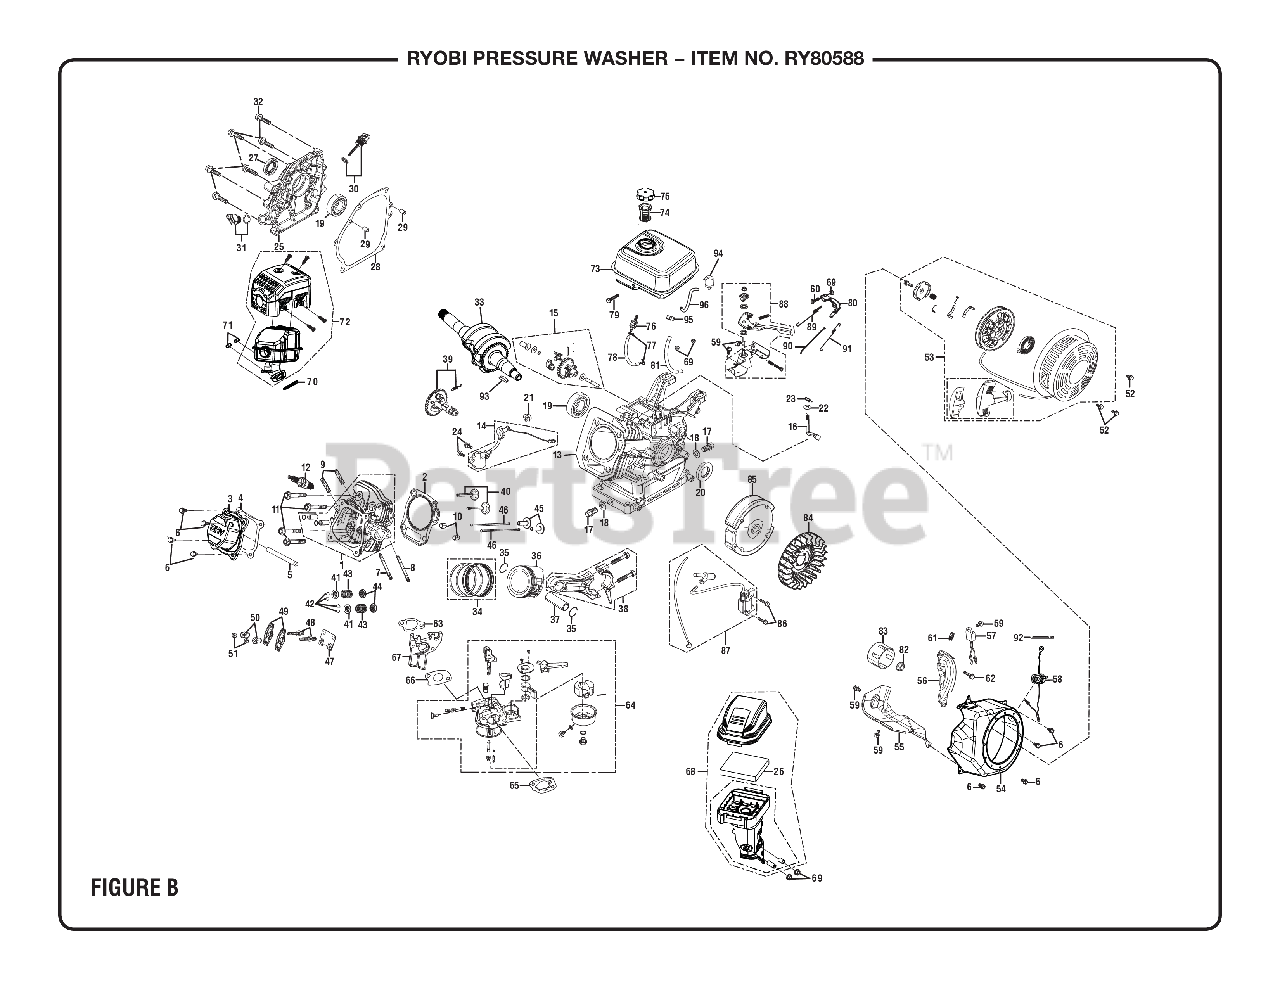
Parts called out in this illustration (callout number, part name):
1	Cylinder Head Assembly
2	Cylinder Head Gasket
3	Cylinder Head Cover Sub-assembly
4	Cylinder Head Cover Gasket.
6	Bolt (need size)
11	Bolt (Cylinder Head)
13	Crankcase Assembly
14	Engine Oil Sensor
15	Governor Gear Assembly
17	Drain Plug Bolt
19	Ball Bearing
22	Governor Gear Washer
25	Crankcase Cover Assembly
26	Air Cleaner Element Assembly
28	Crankcase Gasket
30	Oil Dipstick Sub-assembly
31	Engine Oil Plug Assembly
33	Crankshaft Assembly
34	Piston Ring Assembly
35	Piston Pin Clip
36	Piston Assembly
39	Camshaft Assembly
41	Valve Spring Seat
42	Valve Lock Clamp
47	Lifter Stopper Plate Sub-assembly
48	Valve Adjustment Bolt
50	Valve Adjustment Nut
53	Recoil Starter Assembly
55	Shroud (flasque de cylindre)
58	Stop Engine Switch Assembly
60	Governor Support Bolt,
63	Carburetor Insulator Gasket..
64	Carburetor Assembly
65	Air Cleaner Gasket
66	Carburetor Gasket
67	Carburetor Insulator Plate
69	Governor Support Assembly
70	Exhaust Outlet Gasket
71	Nut (need size)
72	Muffler Assembly
75	Fuel Tank Cover
76	Fuel Tank Oil Outlet Assembly
80	Governor Support Sub-assembly
85	Flywheel Sub-assembly
88	Throttle Control Assembly
89	Governor Spring
91	Throttle Valve Returning Spring
94	Fuel Tank Vapor Vent
96	Fuel Steam Rubber Hose
